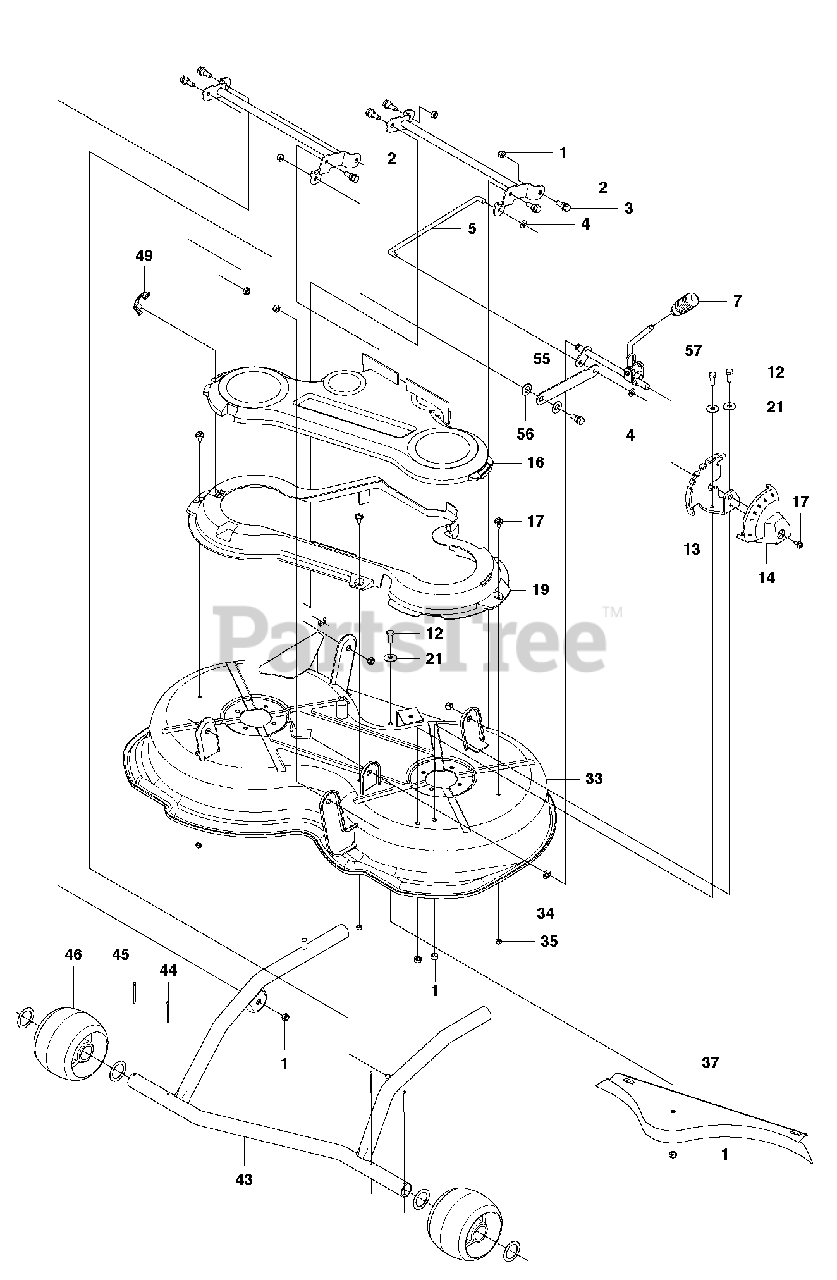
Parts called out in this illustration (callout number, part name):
1	LOCKNUT M8
34	RETAINING RING
35	LOCKNUT M6
44	COTTER PIN
56	WASHER - 25X8.5X2.3
